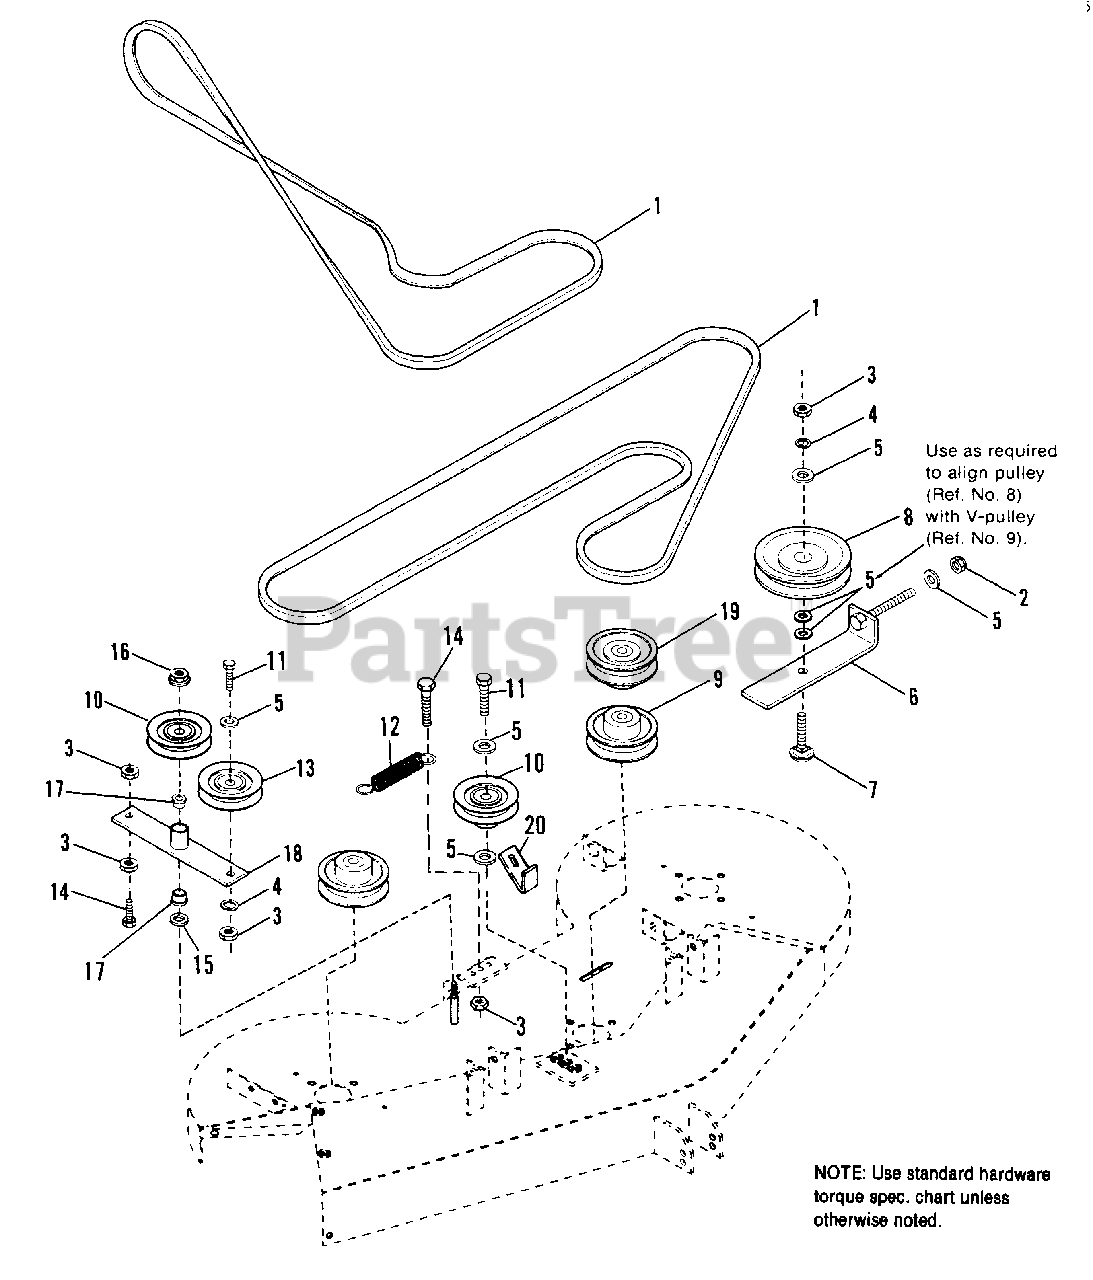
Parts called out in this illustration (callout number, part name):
1	V-BELT, Mower
2	NUT, Fiber Lock, 3/8-16
3	NUT, Hex, 3/8-16
4	LOCKWASHER, Spring, 3/8
5	WASHER, Plain
6	DRAW BRACKET ASSY.
7	CARRIAGE BOLT, 3/8-16 x 2
8	V-PULLEY, Idler
9	V-PULLEY, Drive
10	V-PULLEY, Idler
11	CAPSCREW, Hex, 3/8-16 x 1-3/4
12	SPRING, Extension
13	PULLEY, Idler, Backside 3-1/2" dia.
14	CAPSCREW, Hex, 3/8-16 x 1-1/2
15	WASHER, Plain (Use as required)
16	NUT, Lock, Hex, Flanged, 3/8-16
17	BEARING, Nylon, Flanged
18	IDLER ARM ASSY.
19	V-PULLEY, Drive
20	RETAINER, Belt
